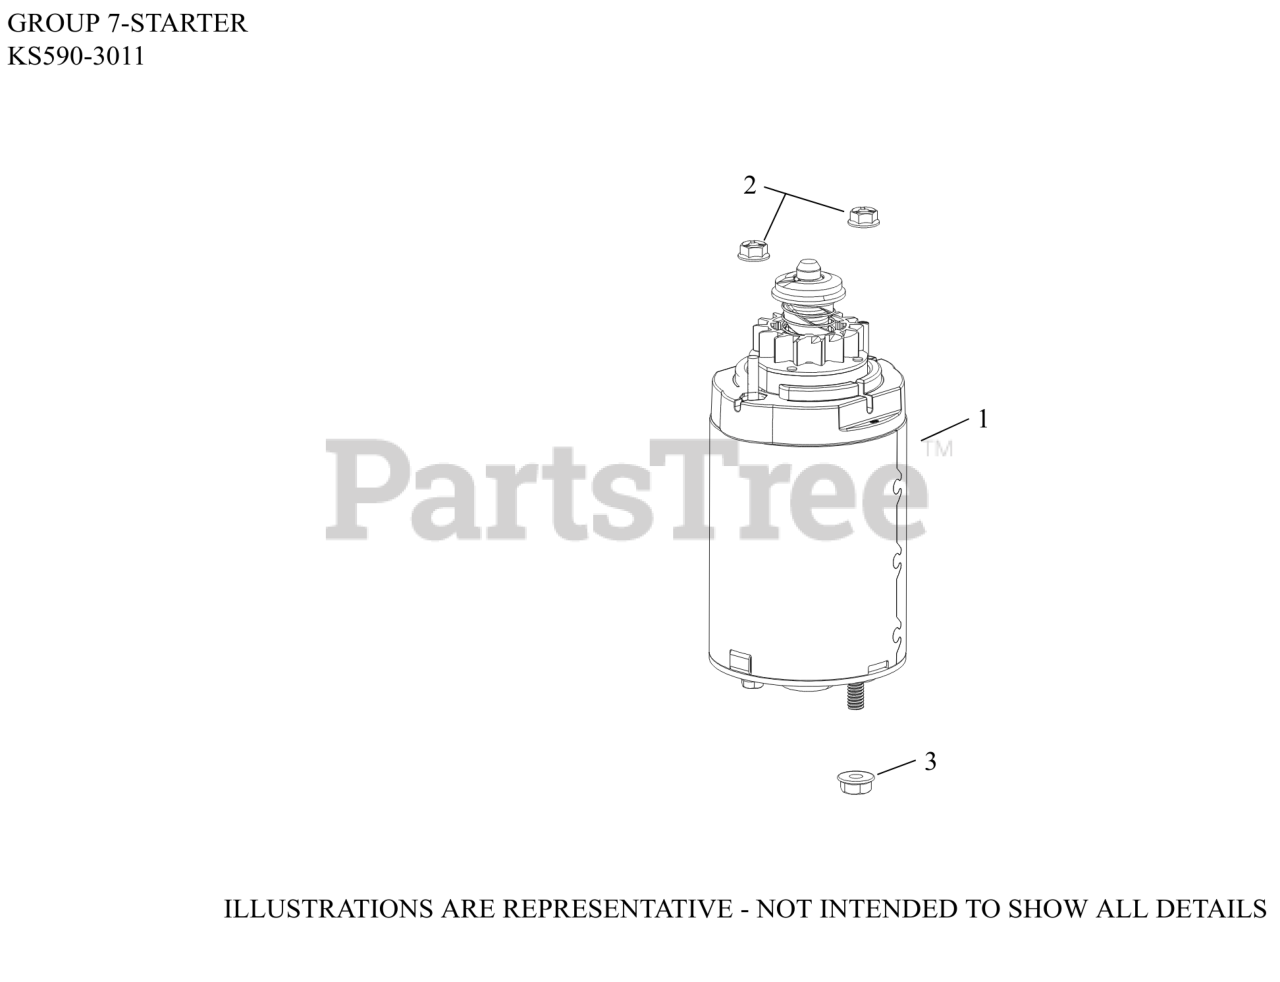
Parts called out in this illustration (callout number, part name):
1	STARTER, ASSY
2	NUT, HEX FLANGE LOCK (10-24)
3	NUT, FLANGE 1/4-20
